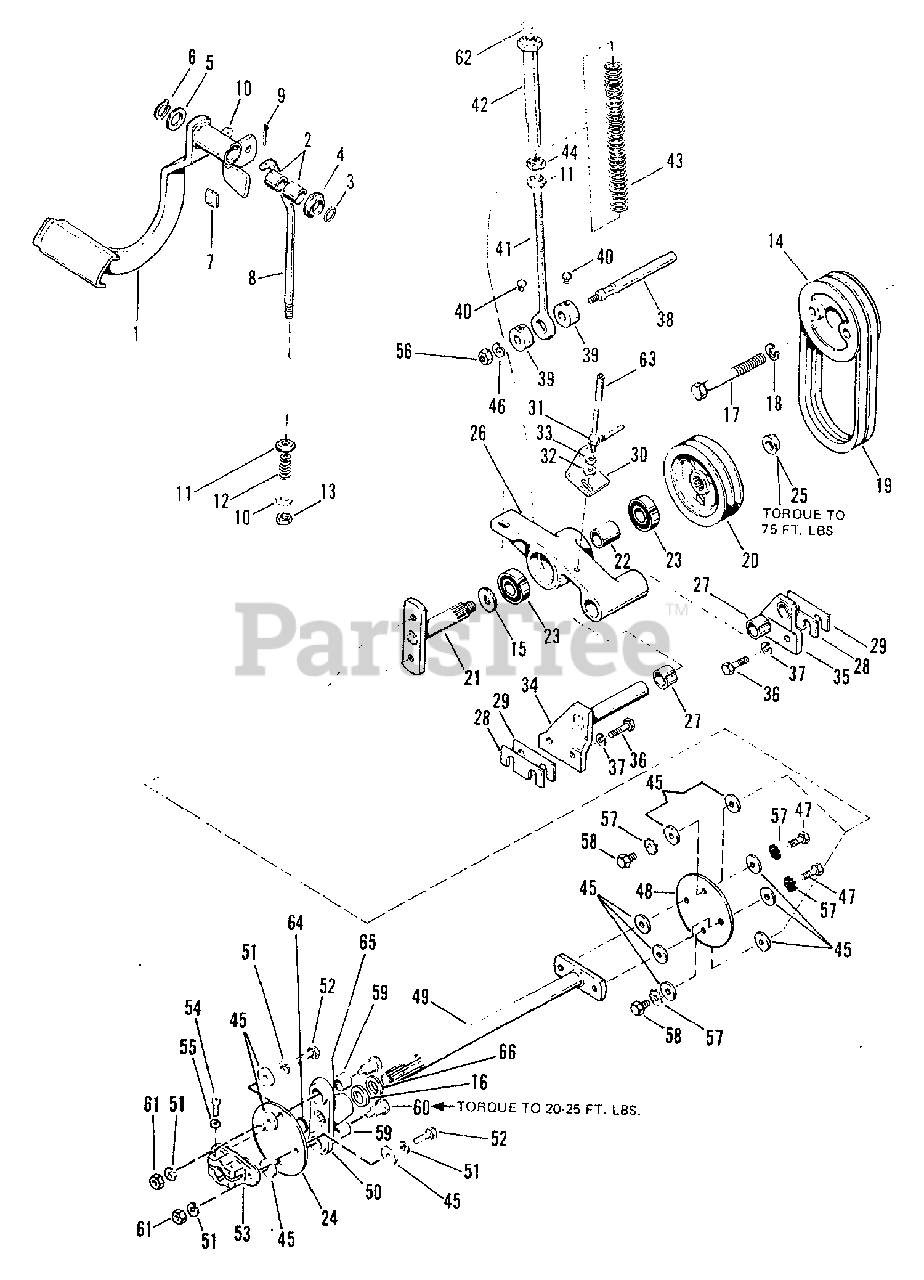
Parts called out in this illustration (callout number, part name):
1	LEVER ASSEMBLY
2	SLEEVE, Bearing
3	RING, Retaining
6	RING, Retaining
8	ROD, Clutch
9	PIN, Cotter
10	WASHER, Plain, 3/8"
11	SPACER, Clutch
13	NUT, Hex, Lock, 3/8-16
14	PULLEY, Input
16	WASHER, Felt
17	CAPSCREW, Hex, 7/16-14 x 4-1/2" Lg.
18	LOCKWASHER, 7/16"
19	BELT, "V", Matched Pair
20	PULLEY, Input
21	SHAFT ASSEMBLY
25	LOCKNUT, Washer Base
26	ARM, Pivot
27	SLEEVE, Bearing
30	STOP, Belt
31	CAPSCREW, Hex, 5/16"-18 x 3/4" Lg.
32	WASHER, Plain
33	LOCKWASHER
34	SUPPORT ASSEMBLY
35	SUPPORT ASSEMBLY
36	CAPSCREW, Hex, 3/8"-1-1/4" Lg.
37	LOCKWASHER, 3/8"
38	SHAFT, Pivot
39	COLLAR, Set
40	SCREW, Set, 5/16"-18 x 5/16"
41	BOLT, Eye
42	TUBE ASSEMBLY
44	NUT, Hex, Jam, 3/8"-16
45	WASHER, Special
46	LOCKWASHER, 3/8"
47	CAPSCREW, Hex, 3/8"-16 x 7/8" Lg.
49	DRIVE SHAFT ASSEMBLY
51	LOCKWASHER, 3/8"
52	CAPSCREW, Hex, 3/8"-16 x 1" Lg.
53	YOKE, Clamp
54	SCREW, Socket Head, 5/16-18 x 1-1/4" Lg.
55	LOCKWASHER, 5/16
56	NUT, Hex, Full, 3/8"-16
57	LOCKWASHER, Shakeproof, 3/8"
58	CAPSCREW, Hex, 3/8"-16 x 7/8" Lg.
60	BOLT, Shoulder
62	PLUG, Hole
63	LINE, Fuel
65	FITTING, Grease
